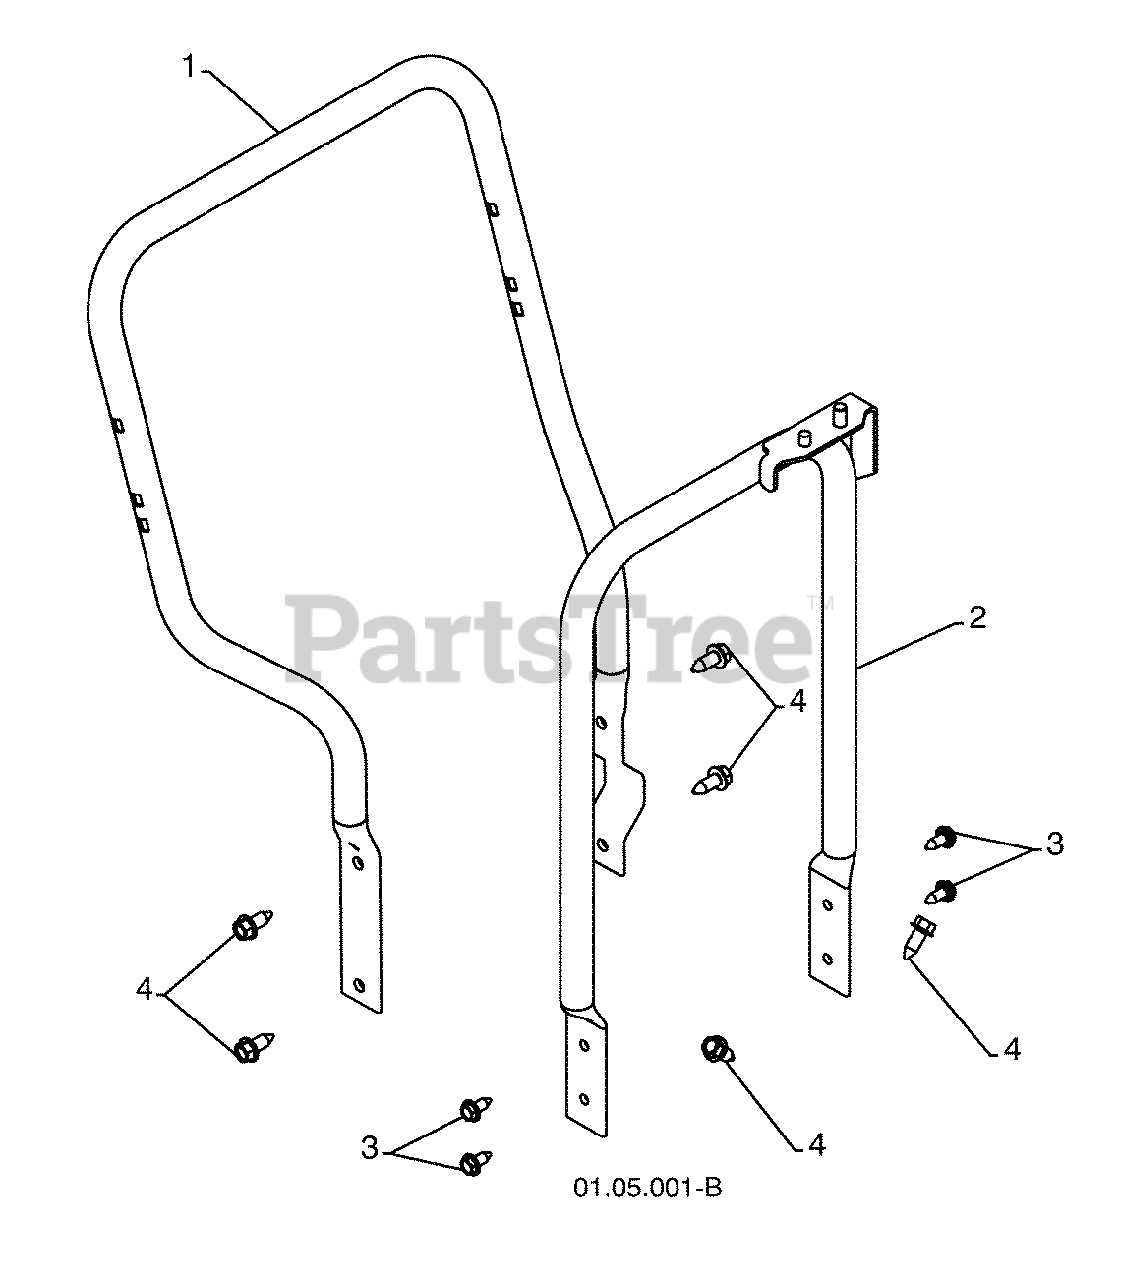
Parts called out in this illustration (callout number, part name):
1	LOWER TUBE
2	PIVOT SUPPORT
3	BOLT 5/16--18 X .750
4	SCREW 3/8--16 X 1.00
